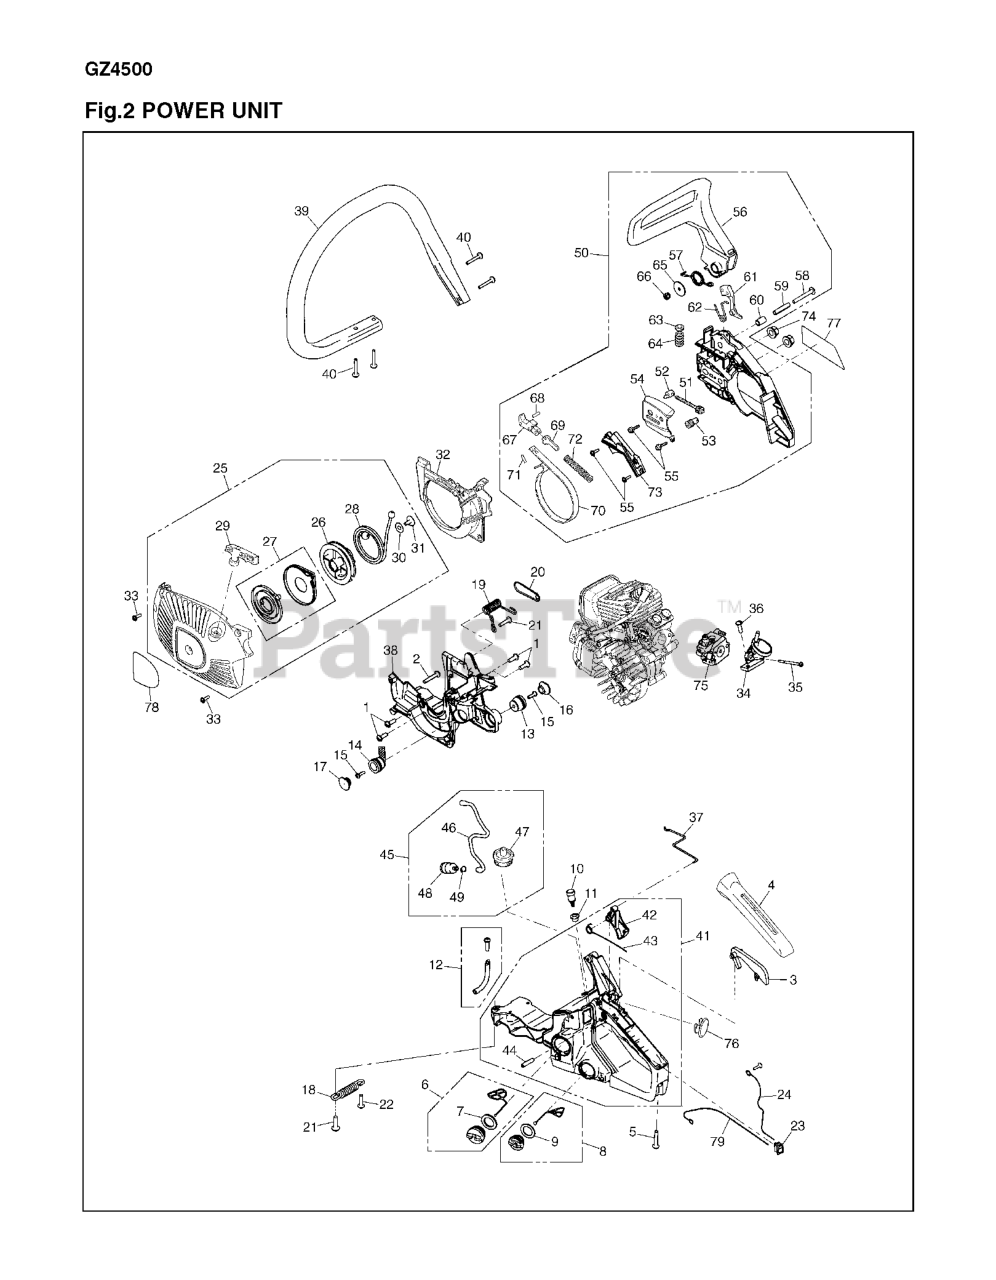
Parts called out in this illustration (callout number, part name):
1	RP_SCREW
3	ARM (RPLS 335633350-335633352)
6	CAP
7	GASKET
8	CAP ASSY
9	GASKET
10	BREATHER
11	GROMMET
12	PIPE COMP (REPL T210031500)
18	SPRING(F)
21	SCREW (RPLS 267132210)
22	RP_SCREW
23	SWITCH
25	STARTER ASSY
31	SCREW (RPLS 267132210)
34	MANIFOLD
37	ROD.THROTTLE
38	CASE, ENGINE
41	HANDLE, RIGHT ASSY
44	SPRING PIN
45	PIPE ASSY
46	PIPE
49	CLIP
50	BRAKE ASSY. (RPLS T212854000)
54	PLATE(B)
55	SCREW
57	RETURN SPRING
58	SCREW
59	SPACER, INNER
60	SPACER
62	SPRING
65	WASHER
67	BRAKE LEVER
68	ROLLER
69	ARM
70	BAND
71	ROLLER
72	SPRING
74	NUT FLANGE
75	CARBURETOR
